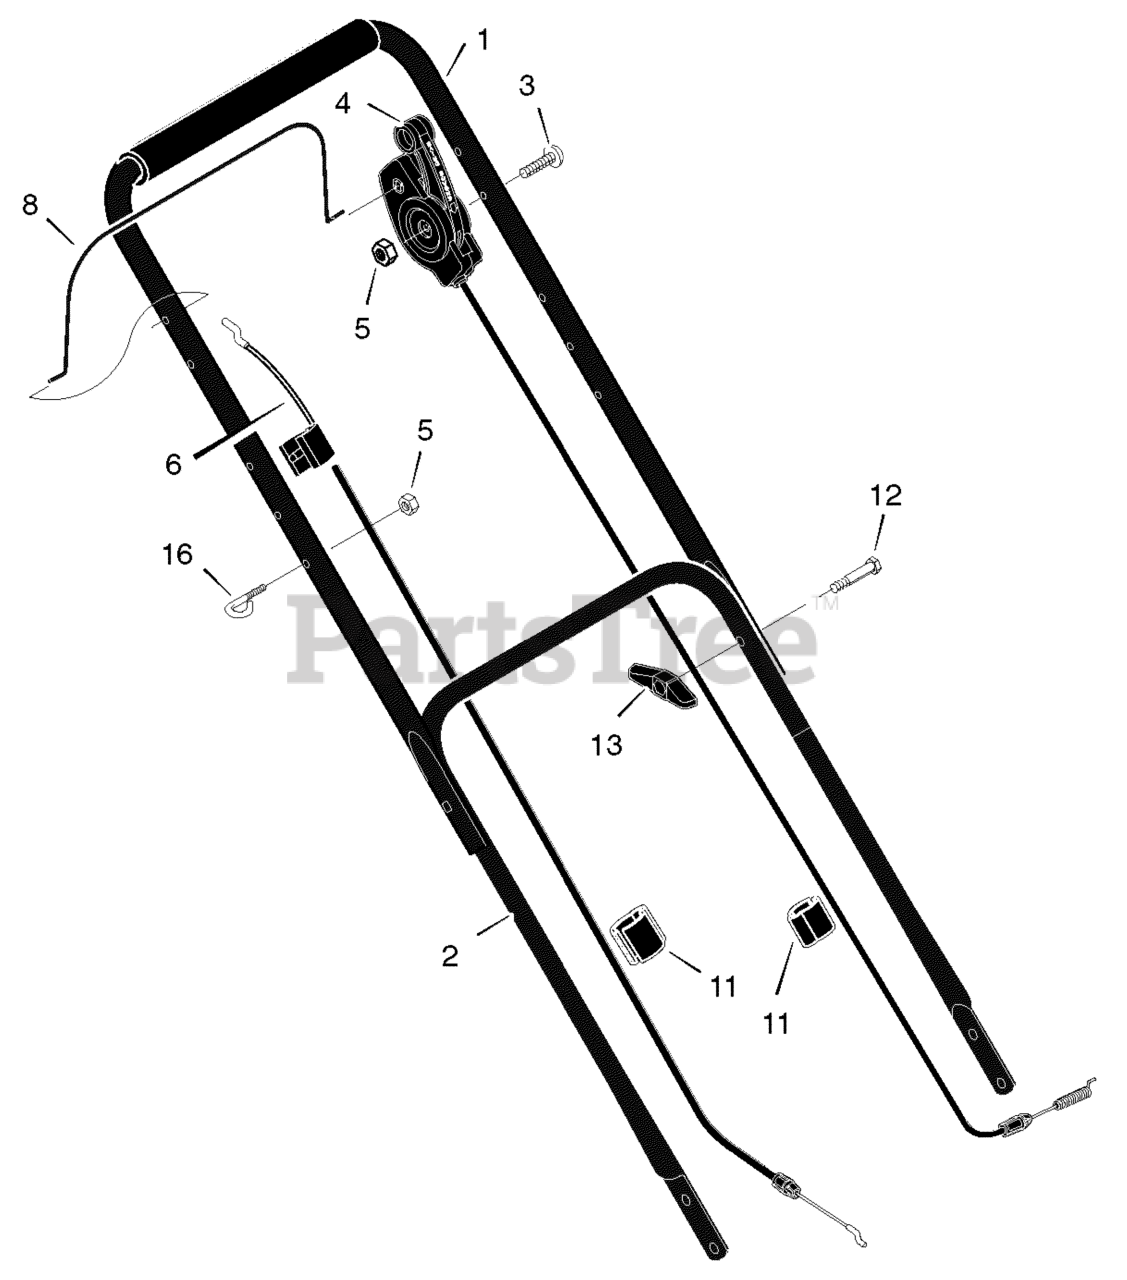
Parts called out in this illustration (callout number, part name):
1	Handle, Upper (Black)
1	Handle, Upper (Gray)
2	Handle, Lower (Black)
2	Handle, Lower (Gray)
4	Control, Drive
5	Locknut
6	Cable, Stop *
8	Lever, Stop
11	Fastener, Cable
13	Knob
16	Guide, Rope
